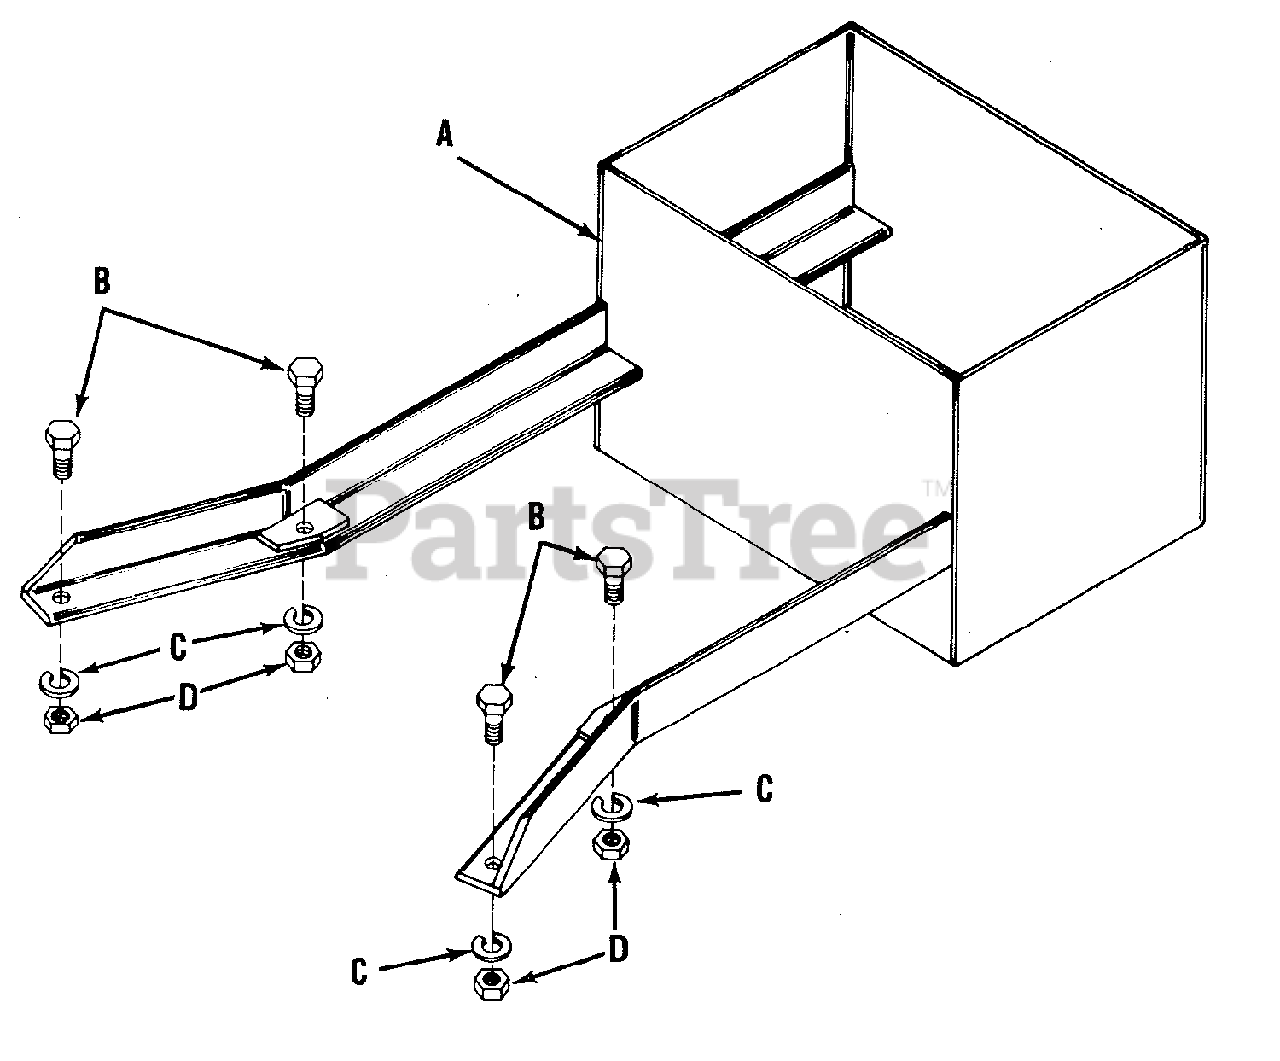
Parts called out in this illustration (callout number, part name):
A	BOX, Weight
B	CAPSCREW, Hex, 1/2"-13 NC x 1-1/4"
C	WASHER, Lock, 1/2"
D	NUT, Hex, Full, 1/2"-13 NC
